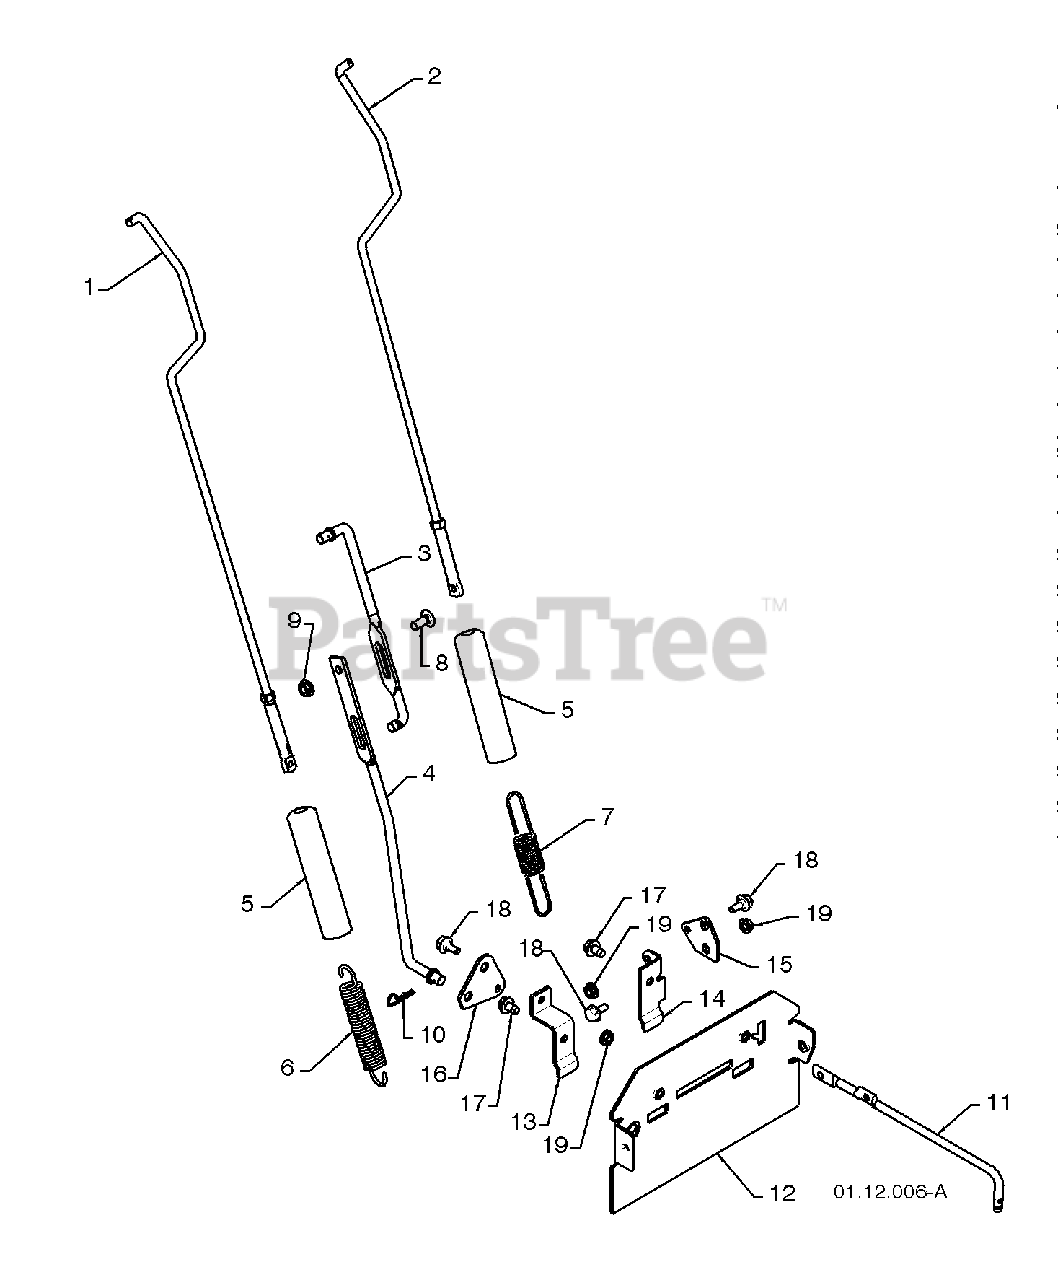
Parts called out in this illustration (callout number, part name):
1	IMPELLER ROD ASSEMBLY
2	TRACTION ROD ASSEMBLY
3	SHIFTER ROD TOP
4	SHIFTER ROD BOTTOM
5	SPRING SLEEVE
6	IMPELLER SPRING
7	TRACTION SPRING
8	CARRIAGE BOLT 5/16-18 X .750
9	NUT 5/16-18
11	CLUTCH ROD
12	REAR PLATE
13	SHIFTER PLATE BRACKET
14	CLUTCH PLATE BRACKET
15	CLUTCH PLATE
16	SHIFTER PLATE
17	BOLT 5/16-18 X .500
18	SHOULDER BOLT 1/4-20 X .500
19	NUT 1/4-20
